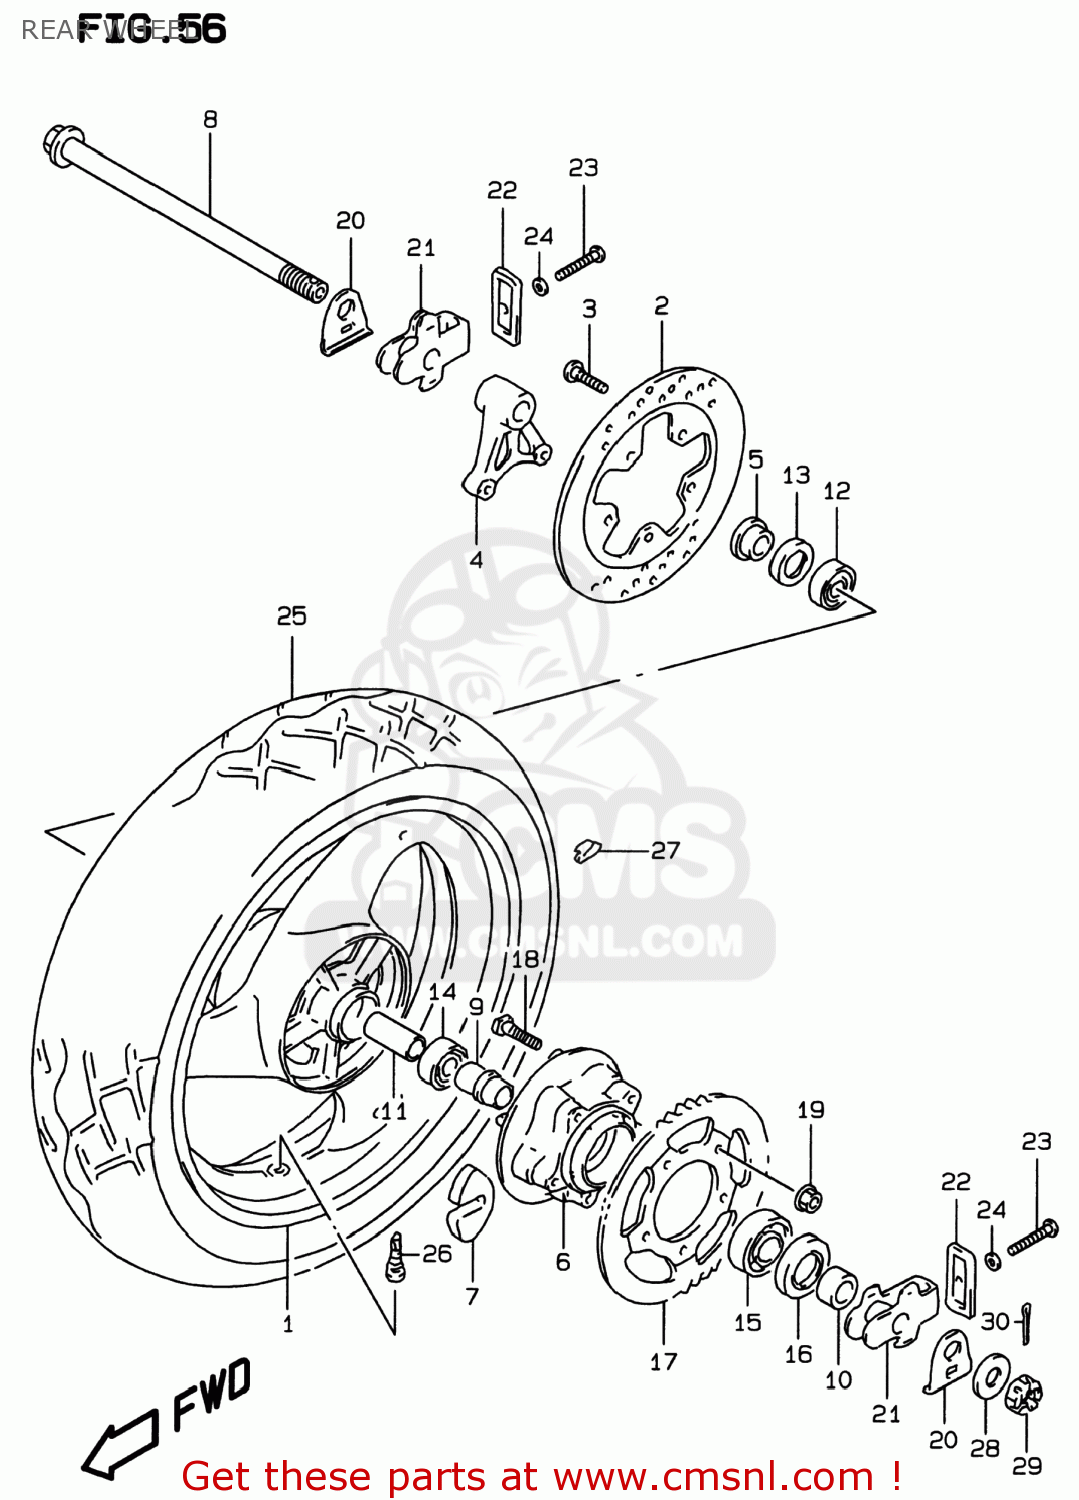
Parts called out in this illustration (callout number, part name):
1	WHEEL,RR(MT4.50X17)
2	DISC,RR BRAKE
3	BOLT 8X33
4	BRACKET,RR CALIPER
5	SPACER,RR AXLE,R
6	DRUM,RR SPROCKET
7	ABSORBER,RR HUB SHOCK
8	AXLE,RR
9	RETAINER,RR HUB BEARING
10	SPACER,RR AXLE,L
11	SPACER(20.8X27.2X97)
12	BEARING
13	SEAL,OIL(28X47X7)
14	BEARING(20X47X14)
15	BEARING(25X62X17)
16	SEAL,OIL(35X62X8)
17	SPROCKET,RR(NT:48-530)
18	BOLT(10X47)
19	NUT
20	WASHER,CHAIN ADJUSTER
21	ADJUSTER,CHAIN
22	PLATE,CHAIN ADJUSTER GUIDE
23	BOLT(8X50)
24	WASHER
25	TIRE,REAR 150/70-17 69
26	VALVE ASSY,WHEEL RIM(TR412)
27	BALANCER,WHEEL (10G)
28	WASHER(18.5X28X2.6)
29	NUT
30	PIN, COTTER
